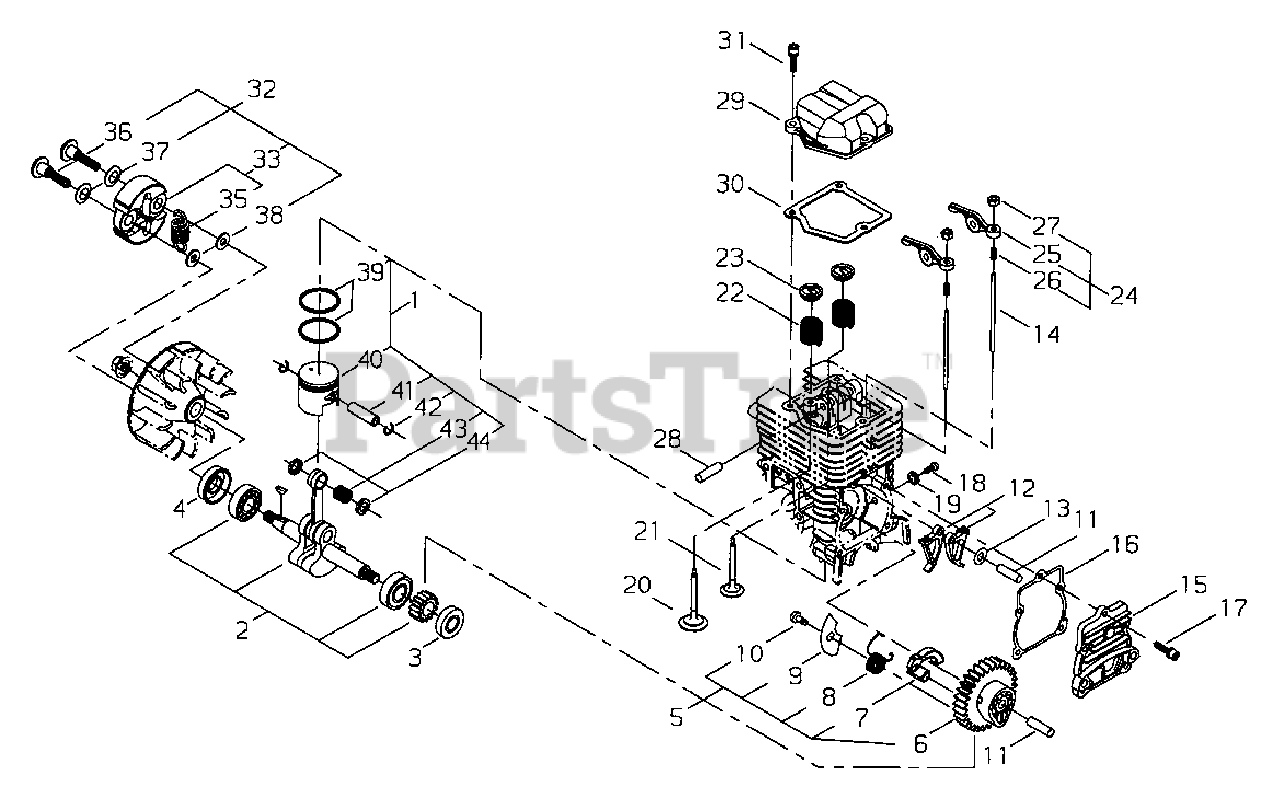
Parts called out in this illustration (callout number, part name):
1	PISTON KIT
2	CRANKSHAFT ASSY
3	SEAL, OIL - 12
4	SEAL, OIL - 12
5	CAM GEAR ASSY
6	GEAR, CAM
7	WEIGHT
8	SPRING
9	PLATE
10	SCREW - 4X6 -- TAPPING
11	PIN - LOCATING
12	FOLLOWER, CAM
13	WASHER - 5
14	PUSHROD
15	COVER, CAM GEAR
16	GASKET
17	SCREW - 4X14
18	SCREW - 5
19	WASHER
20	VALVE, INTAKE
21	VALVE, EXHAUST
22	SPRING, VALVE
23	VALVE RETAINER ASSY
24	ROCKER ARM ASSY
25	ARM, ROCKER
26	SCREW, ADJUST
27	LOCKNUT, ADJUSTER
28	SHAFT, ROCKER ARM - 5X31.8
29	COVER, ROCKER ARM
30	GASKET
31	SCREW - 4X12
32	CLUTCH SHOE SET
33	CLUTCH ASSY
35	SPRING, CLUTCH
36	BOLT, CLUTCH
37	WASHER - SPRING
38	WASHER - 6
39	RING, PISTON
40	PISTON
41	PIN, PISTON
42	RING, RETAINING
43	BEARING, NEEDLE
44	SPACER - 9
